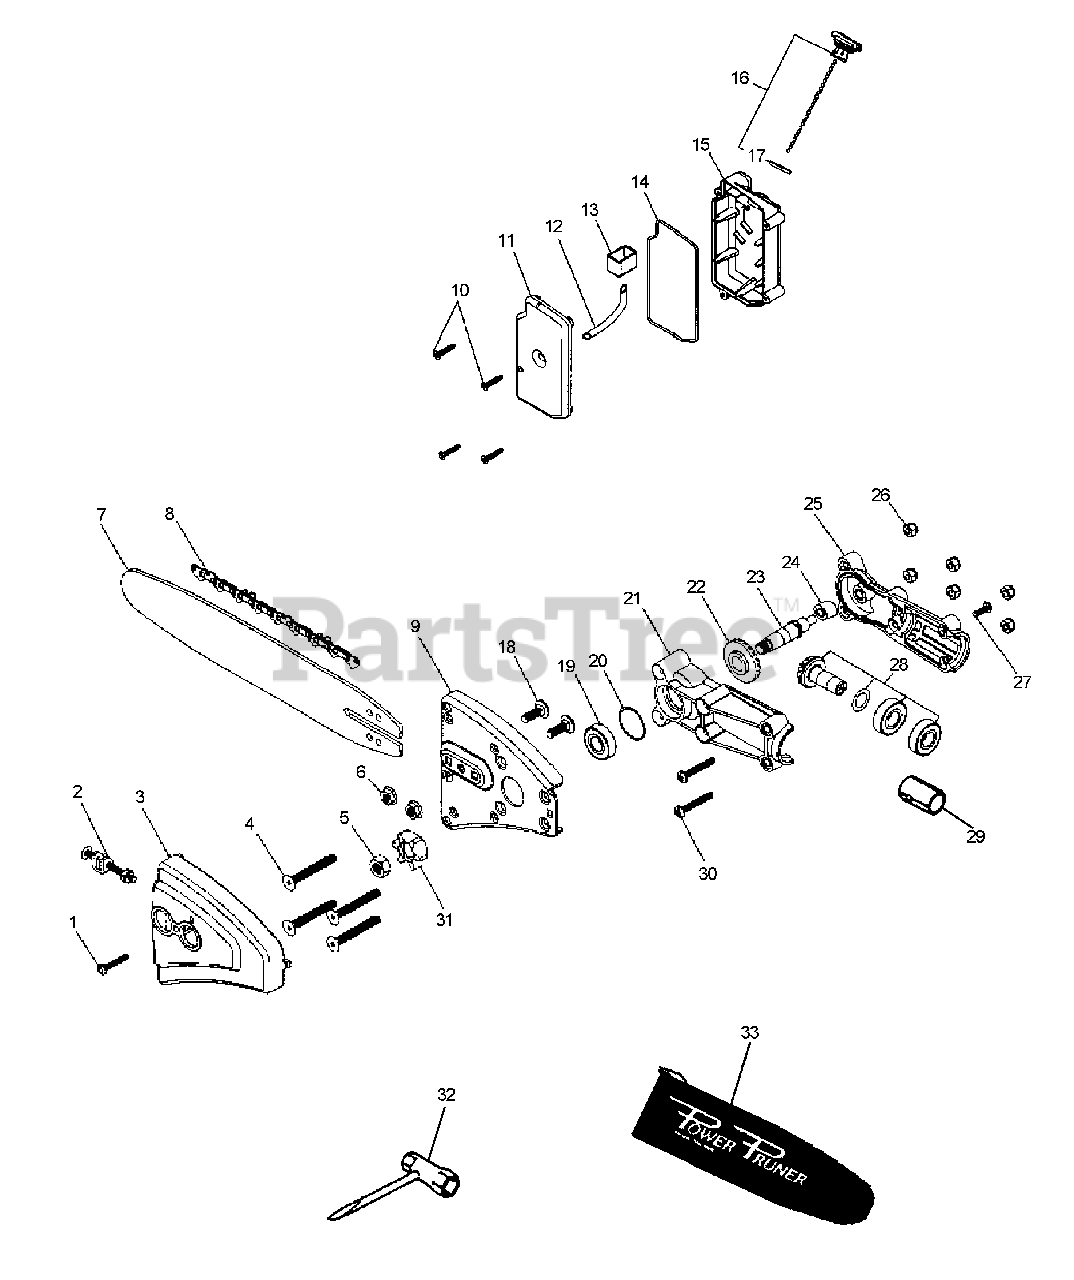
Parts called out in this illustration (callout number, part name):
1	SCREW - 8-32×1" - TORX PAN HEAD
2	TENSIONER KIT
3	GUARD, SPROCKET
4	SCREW - TORX FLAT HEAD
5	NUT, HEX
6	NUT - FLANGE
7	GUIDE BAR - 12" -- 91 VG
8	SAWING CHAIN - 91VS - 12" -- LOW PROFILE
9	SAW BAR CARRIER
10	SCREW, PH. F.H. M.S.
11	TANK, OIL
12	PIPE, FUEL 3x-5x-70 BLACK
13	CUP, OIL
15	TANK, OIL
16	CAP, OIL
18	BOLT, CARRIAGE
19	BEARING, BALL 6001 DDU
20	SHIM 0.004"
21	CASE, GEAR - RIGHT
22	GEAR, BEVEL
23	SHAFT, GEAR
24	GUIDE, DRIVESHAFT
25	CASE, GEAR - RIGHT
26	NUT, LOCK 10-24 UNC
27	SCREW - TORX PAN HEAD
28	SHAFT, GEAR
29	COLLAR - 22
30	SCREW, TORX 10-24 UNC 1-1/4
31	SPROCKET
32	TOOL, BOX SPANNER
33	SCABBARD
